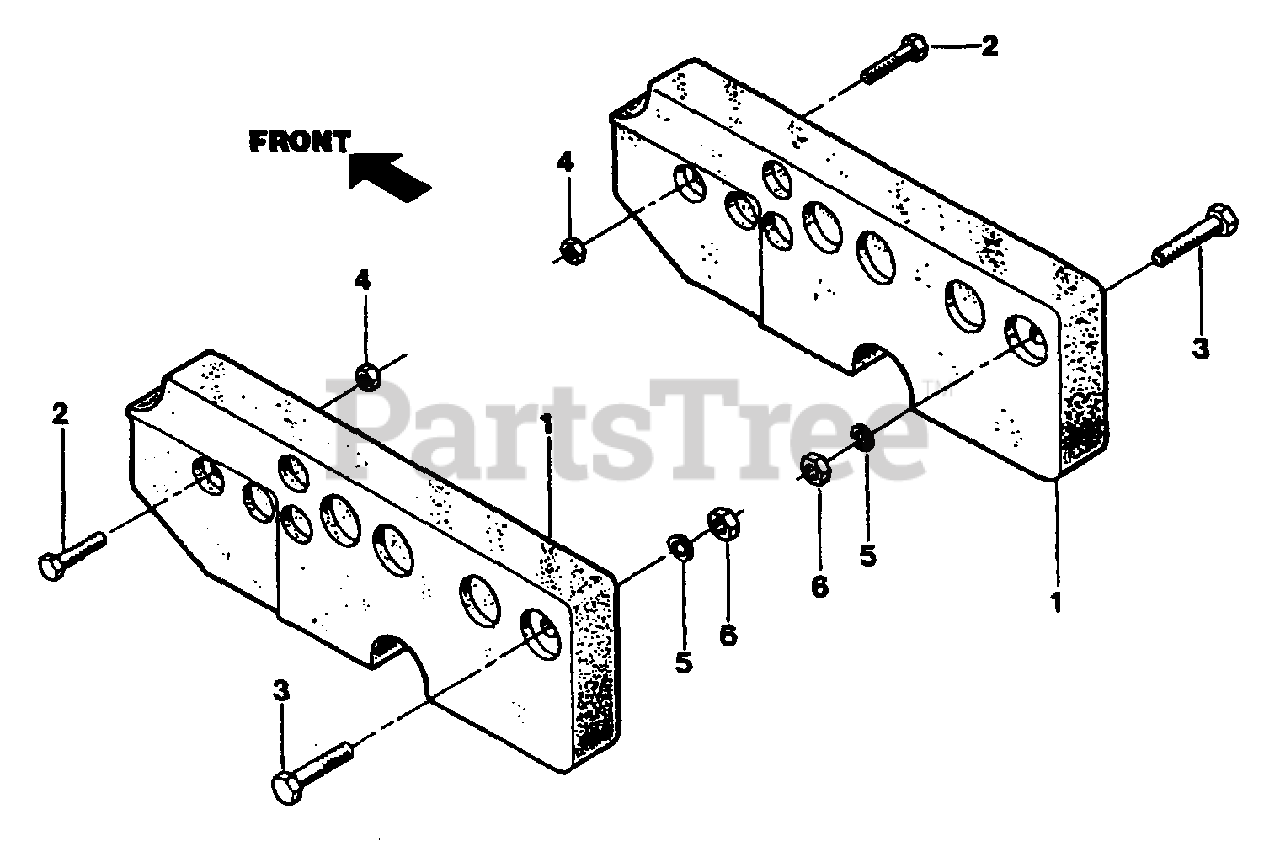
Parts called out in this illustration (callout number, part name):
1	Frame Weight
2	Hex Screw, 1/4-20 x 1-1/4
3	Hex Screw, 5/16-18 x 1-1/2
4	Hex Nut, 1/4-20
5	Lockwasher, 5/16
6	Hex Nut, 5/16-18
